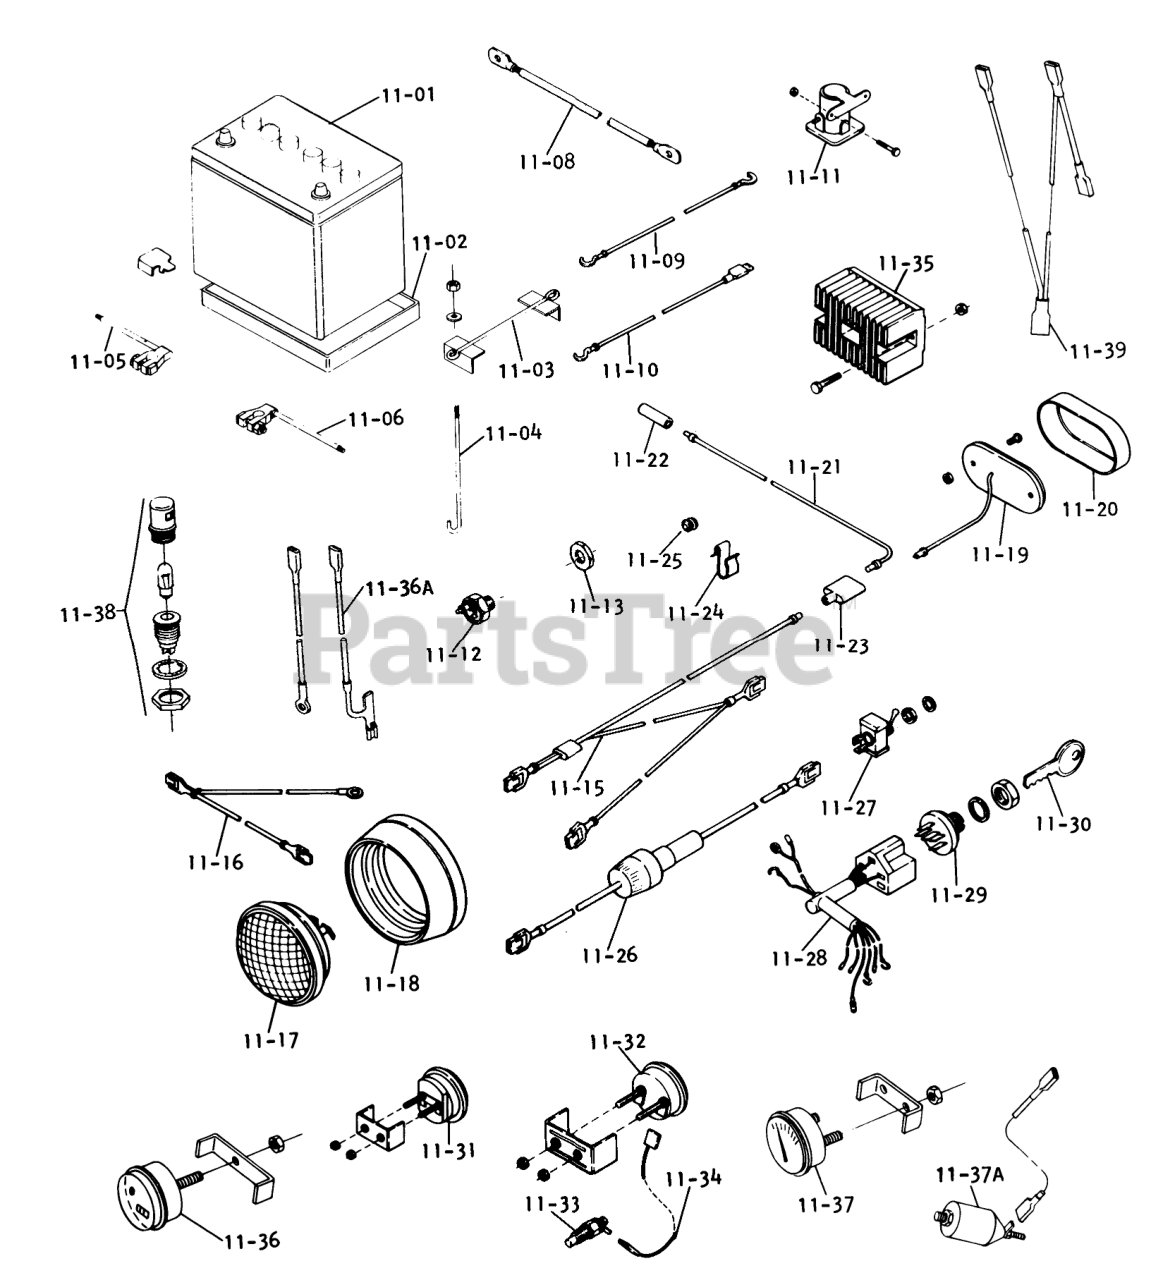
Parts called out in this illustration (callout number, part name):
11-01	Battery
11-02	Battery Box
11-03	Assy-Hold Down
11-04	Hook-Battery Retainer
11-05	ASSY-WIRE SOLENOID
11-06	Wire Assy.-Ground
11-08	Starter-Solenoid 20 1/2"
11-09	WIRE ASSY
11-10	Assy-Wire
11-11	Solenoid
11-12	SWITCH SAFETY
11-13	NUT-SPECIAL 9/16-18
11-15	Control Clip
11-16	Wire Assy
11-17	HEADLAMP
11-18	Grommet
11-19	Base-Taillight
11-20	Lens-Taillight
11-21	Wire assembly
11-22	CONNECTOR 2 WIRE
11-23	CONNECTOR 3 WIRE
11-24	SPEED CLIP
11-25	Grommet
11-26	ASSY FUSED CONNECTOR
11-27	SWITCH-LIGHTS
11-28	Wiring Harness
11-29	SWITCH-IGNITION
11-30	Key-EL
11-31	AMMETER W/CLAMP
11-32	Gauge-Oil Temp
11-33	Assy-Thermistor
11-34	Assy-Wre
11-35	REGULATOR-RECTIFIER
11-36	Hour Meter
11-36A	Wire Assy
11-37	Gauge-Oil Pressure
11-37A	SENDER-OIL PRESSURE
11-38	LAMP-DASH
11-39	Assy-Wire Gauge
11-40	Bracket
